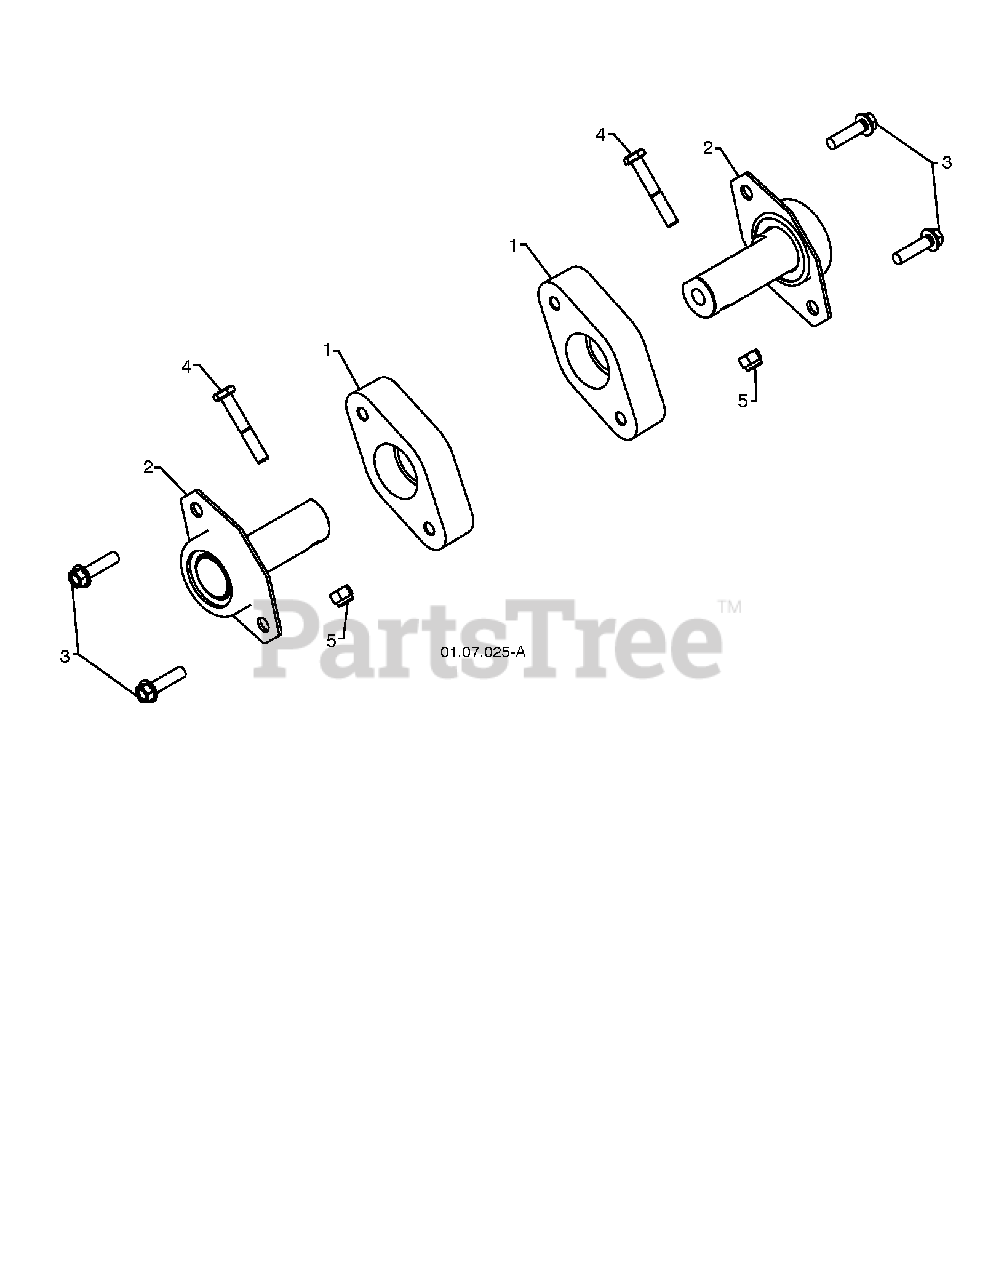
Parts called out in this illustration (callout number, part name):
1	RETAINER.PLASTIC
2	RP BEARING.BALL.AUGER.FLAT.
3	SCREW, HEX HD 5/16X1
4	SCREW.HEX.HD1/4-20X
5	LOCKNUT
